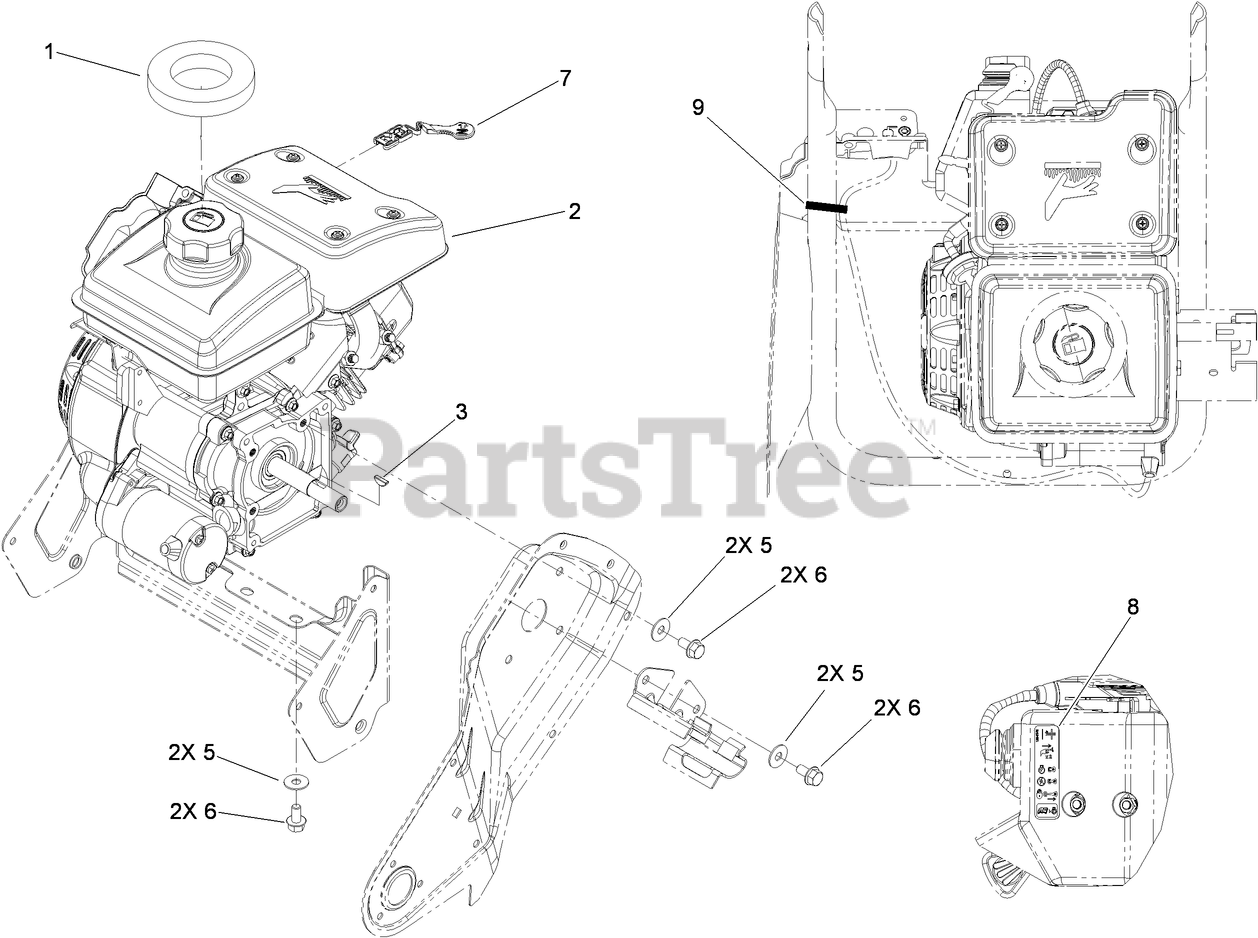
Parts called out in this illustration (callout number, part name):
1	SEAL-TANK
2	ENGINE-154FDS-1
3	KEY-WOODRUFF
5	WASHER-BELLEVILLE
6	SCREW-HHF
7	LEVER-CHOKE
8	DECAL-CONTROL, ENGINE
9	TIE-CABLE
